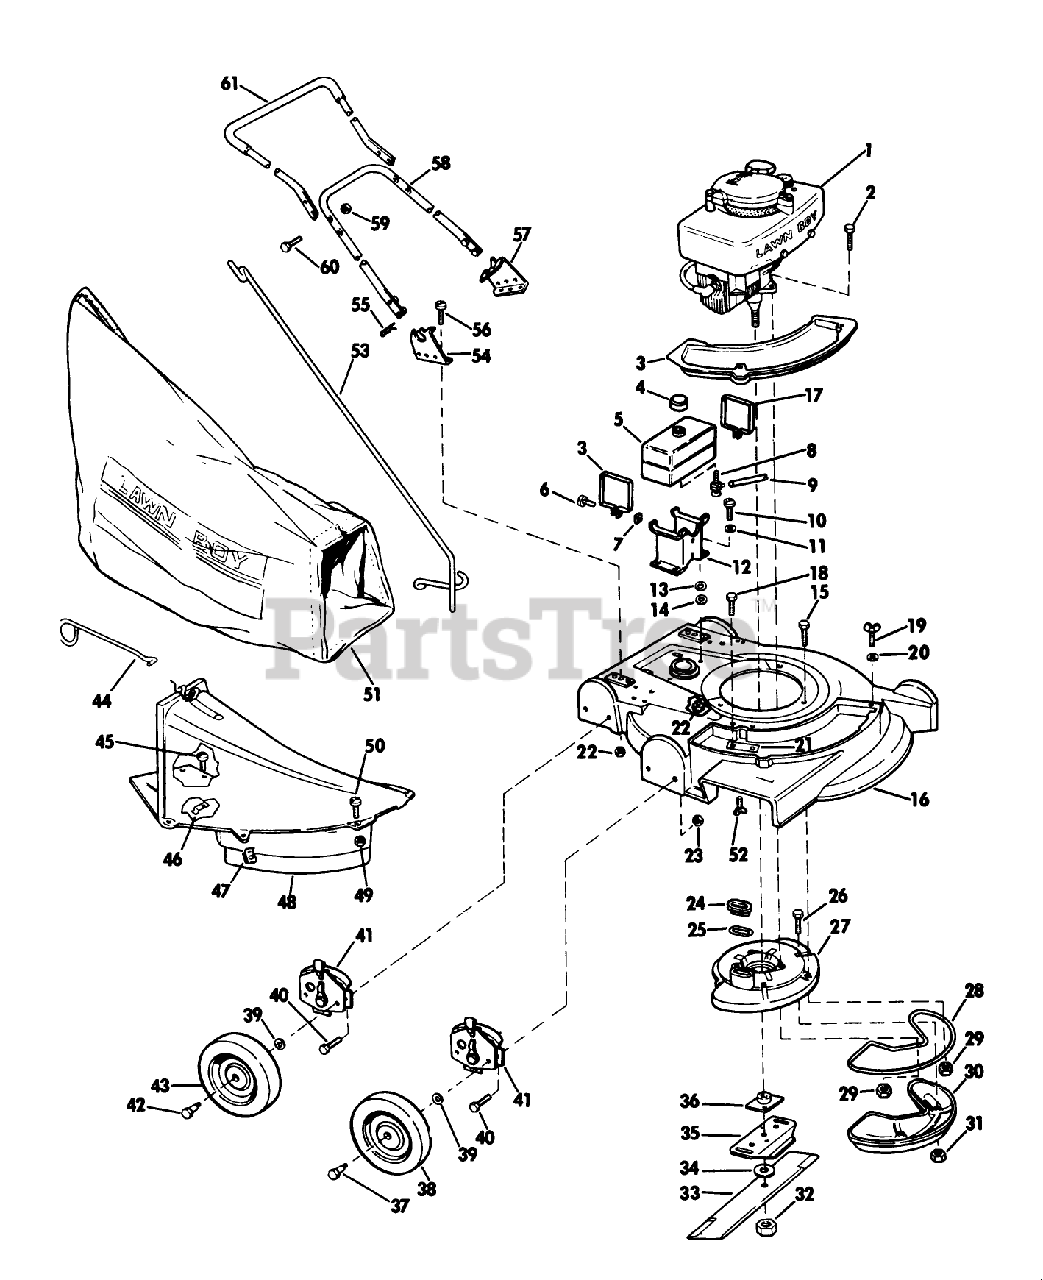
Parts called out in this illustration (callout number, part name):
8	VALVE&SCREEN SM
23	Nut-Nylok
24	Sleeve-Muffler Gasket
25	GASKET S
31	LOCKNUT E
32	NUT-BLADE
36	PLATE AND COLLAR ASM
37	BOLT WHEEL
39	WASHER WROUGHT
42	BOLT-SHOULDER
47	SPEED NUT ARDEN
48	Chute Skirt Assembly (Includes Hardware)
51	89802 LB WHOLE GOODS
56	SCREW S
59	STOP NUT
61	Handle Grip Assy. Top
